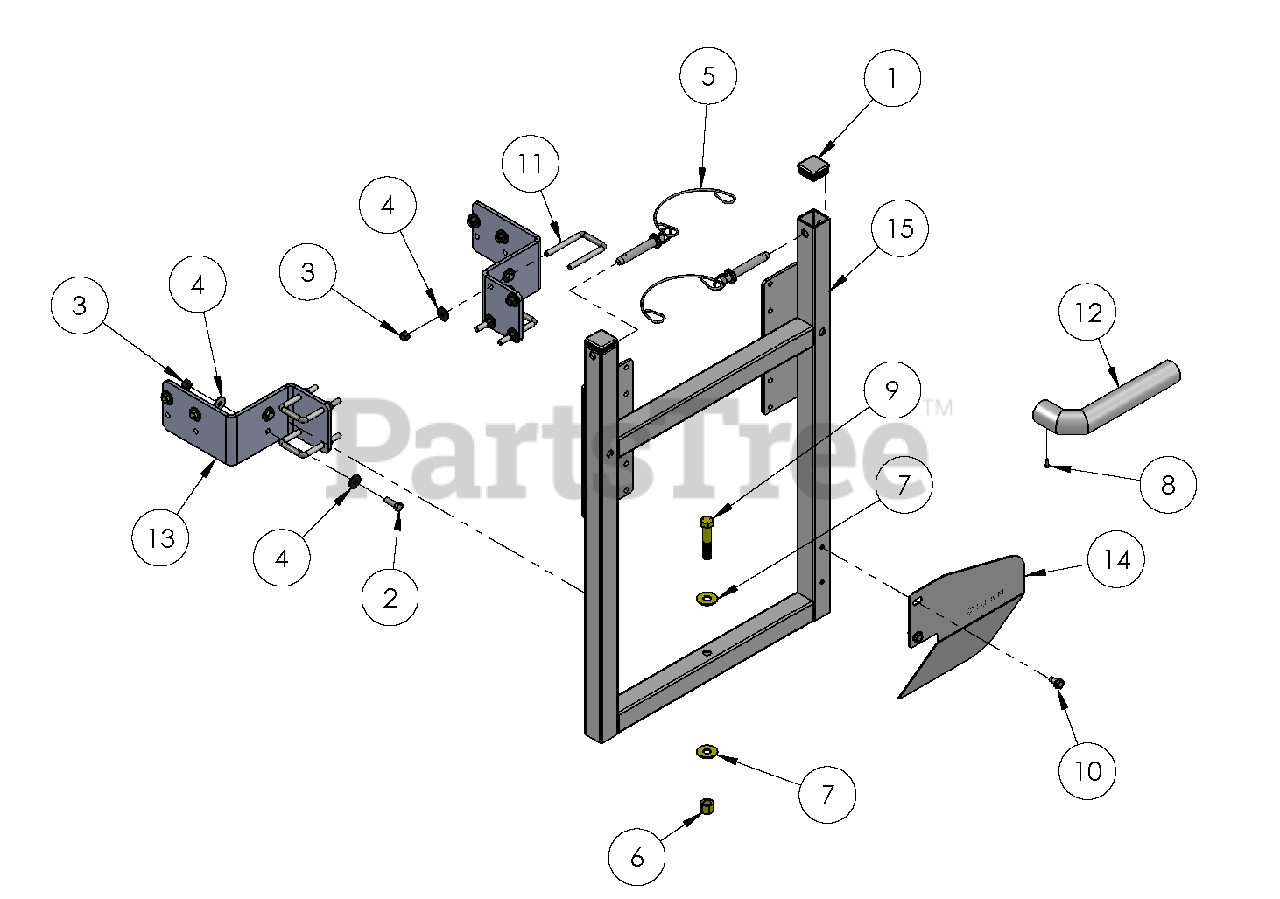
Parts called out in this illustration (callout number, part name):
1	PLUG, SQ. HOLE
2	@BLT-HEX .31-18X1.00 GR5 YWZC
3	@NUT-LK-NYL-FLG .31-18 YWZC
4	@WSHR-FL-STL.344X.688X.065YWZC
5	DETENT PIN W/LANYARD-1/2X2-1/2
6	@NUT-LK-NYL .50-13 YWZC
7	@WSHR-FL-STL.531X1.06X.095YWZC
8	#10 X 1/2" LG SHEET METAL
9	@BLT-HEX .50-13X2.50 GR5 YWZC
10	5/16 X 5/8" SELF TAP SCREW
11	5/16-18 X 2" W X 3" LG SQ
12	EXHAUST EXTENSION ASSEMBLY
13	LEG SET MOUNTING BRACKET - PRO
14	HEAT SHIELD
15	3 BAG CATCHER MOUNT
